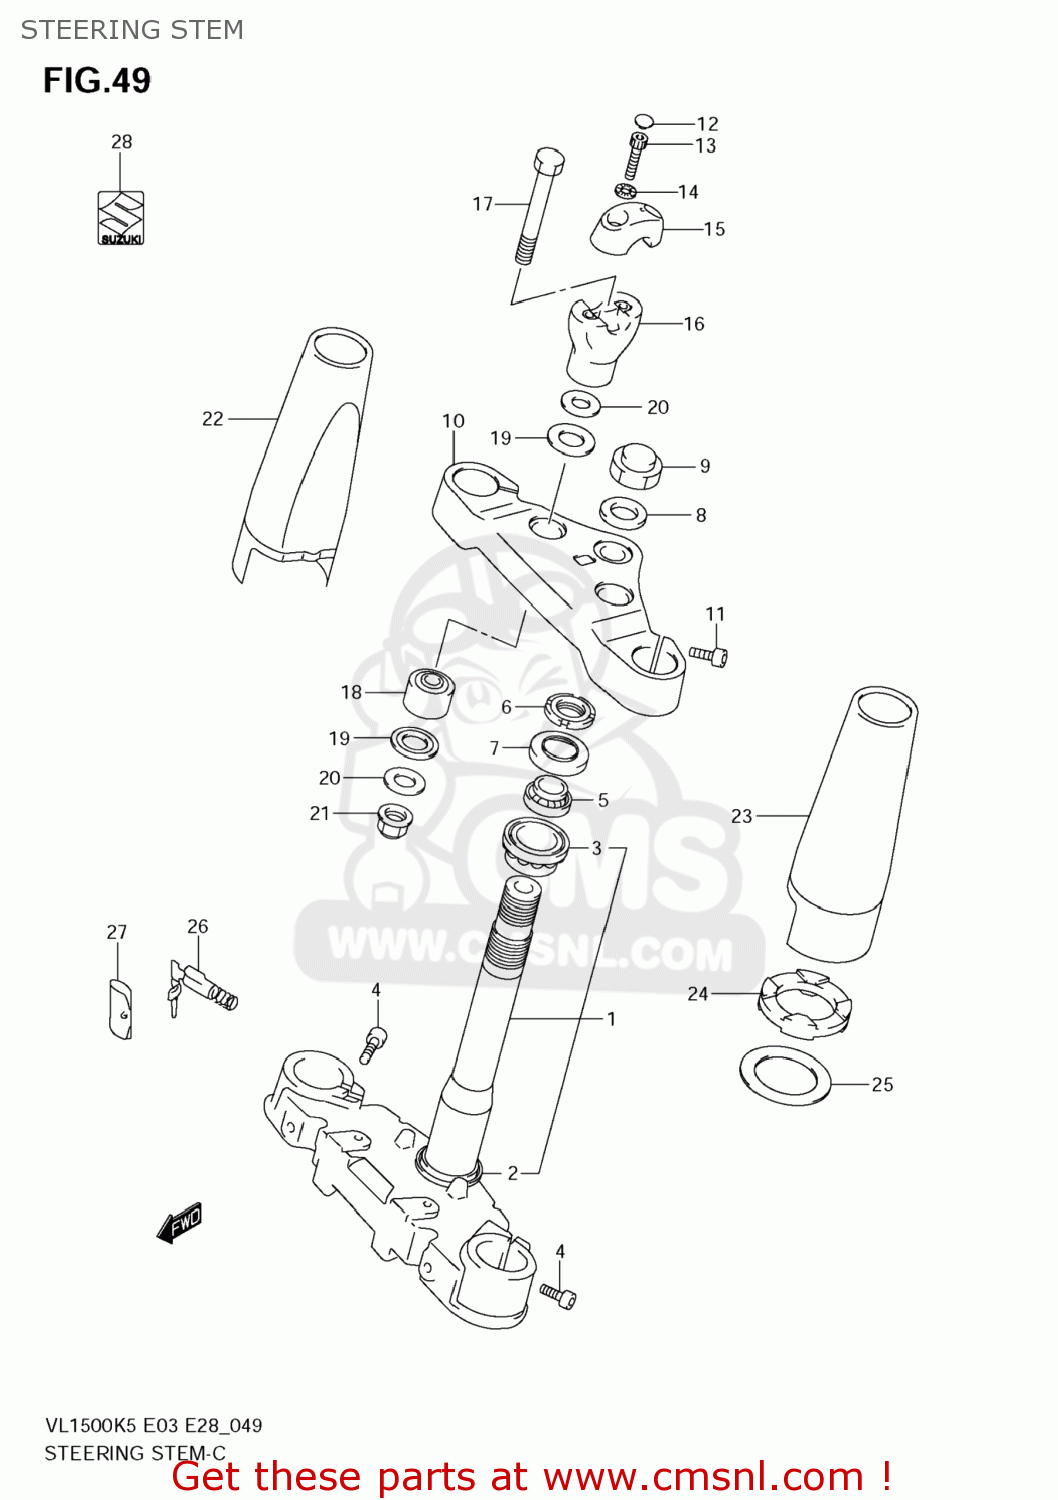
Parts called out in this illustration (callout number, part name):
1	BRACKET,UNDER
2	SEAL,STEERING LWR
3	BEARING(30X55X17)
4	BOLT,STEM
5	BEARING(25X47X15)
6	NUT,STEERING STEM(25X44X10)
7	DUST SEAL,STEERING UPR
8	WASHER(22.5X32X1.6)
9	NUT,CAP
10	HEAD,STEERING STEM
11	BOLT
12	CAP(OD:14.5)
13	BOLT,HANDLE HOLDER
14	WASHER
15	HOLDER,HANDLE UPR
16	HOLDER,HANDLE UNDER
17	BOLT
18	DAMPER,RUBBER
19	SEAT,RUBBER
20	WASHER
21	NUT
22	COVER,UPR,R
23	COVER,UPR,L
24	SEAT,RUBBER
25	WASHER
26	LOCK SET,STEERING
27	CASE,STEERING KEY
28	EMBLEM,S
